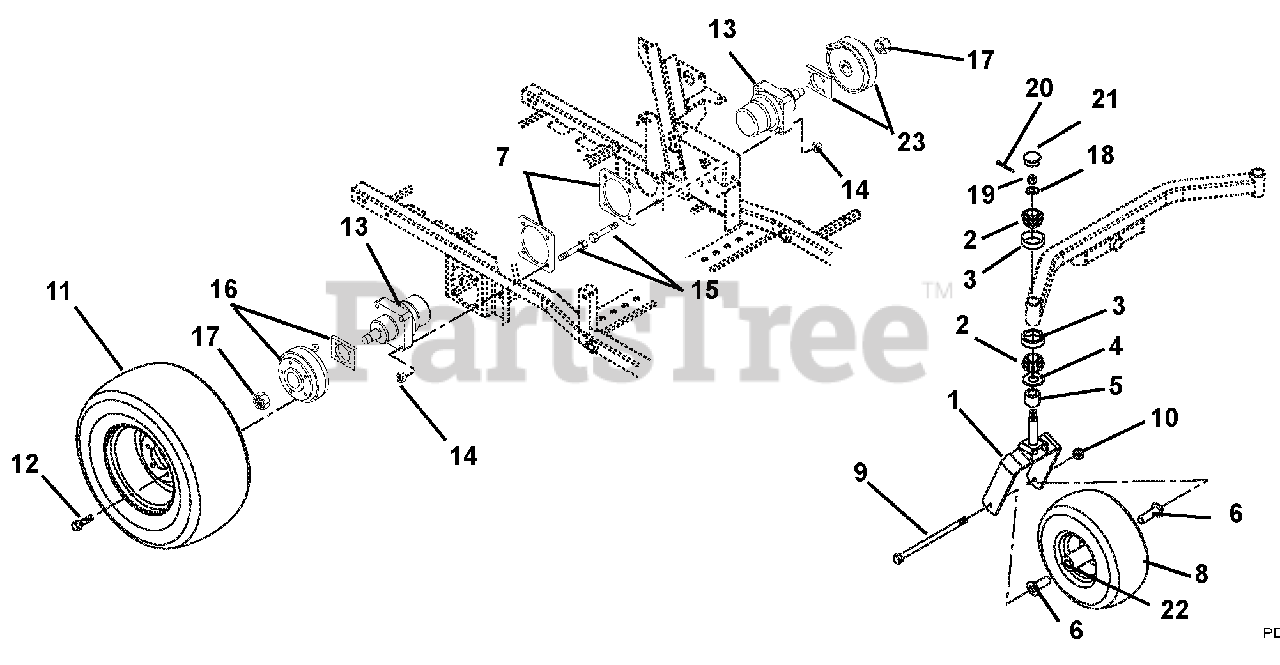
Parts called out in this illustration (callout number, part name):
1	Fork, Front
2	Bearing, Cone w/ Grease
3	Bearing, Cup 1.980 x .420
4	Bearing Seal 1.5 x 2 x .18
5	Spacer, PM, 1.03 I.D. x 1.5 O.D. x .375
6	Spacer, Wheel
7	Plate, Motor Support
8	Wheel/Tire Assembly
9	Bolt, Hex .50-13 x 9.00 Grade 5
10	Nut, Locking Center .50-13
11	Tire/Wheel Assembly 24 x 12-12
12	Bolt, Lug .50-20 x 1.38 Grade 8, 60 Degree
13	Hydraulic Wheel Motor (includes 17)
14	Nut, Locking Top Flange .50-13
15	Bolt, Wheel Motor .50-13 x 2.75
16	Brake, Right Hand Park
17	Nut , Lock Jam Patch (Included with 13)
18	Washer, Flat Steel .755 x 1.375 x .062
19	Nut, Slotted .75-16
20	Pin, Cotter .16 x 1.00
21	Cap, Dust
22	Bearing, 25mm I.D. x 52mm OD x 15mm
23	Brake, Left Hand Park
